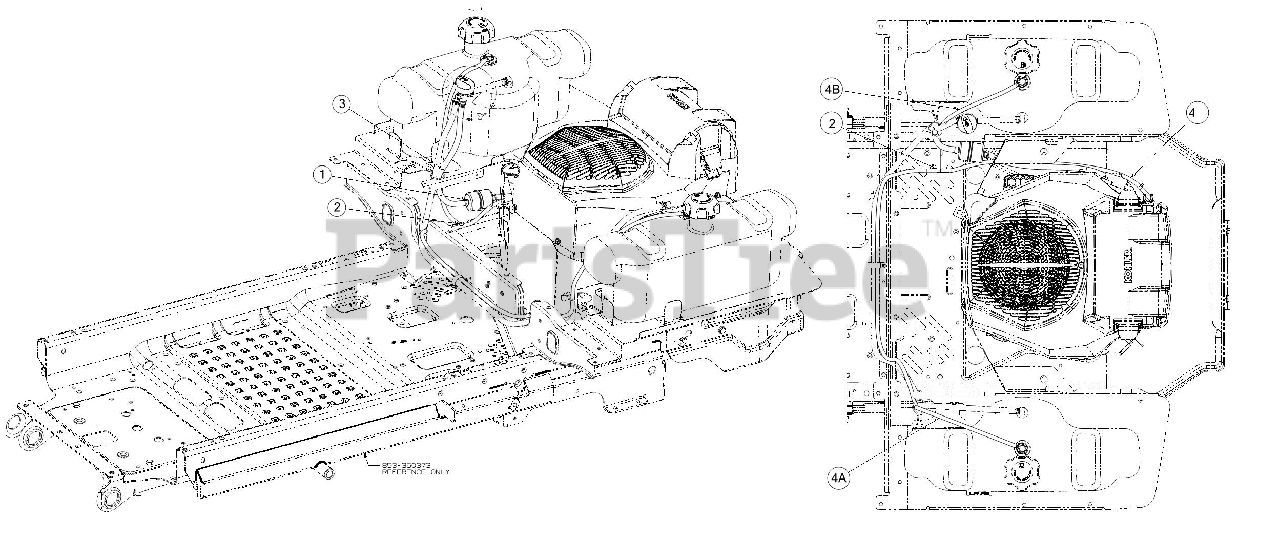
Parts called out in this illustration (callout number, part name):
1	HOSE CLAMP 1/20
2	FUEL FITTING
3	FUEL HOSE LOW PERMEATION
4A	VENT HOSE 3/16 ID
4B	VENT HOSE 3/16 ID
4C	VENT HOSE 3/16 ID
